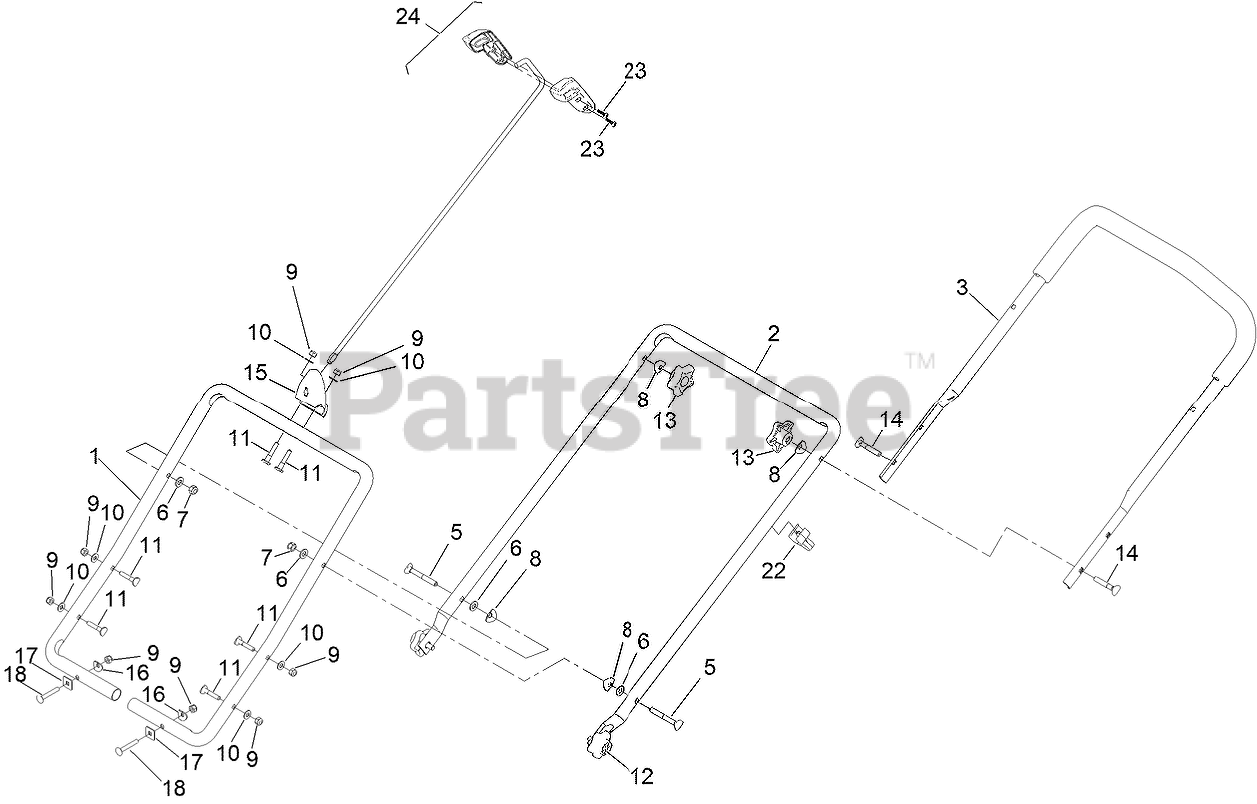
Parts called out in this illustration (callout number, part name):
1	HANDLE-LOWER
2	HANDLE-MIDDLE
3	UPPER HANDLE ASM
5	SCREW-HANDLE
6	WASHER-PLAIN
6	WASHER-FLAT
7	NUT-HEX
7	NUT-LOCK, NI
8	WASHER
8	WASHER-CUP
9	NUT-HEX
9	NUT-LOCK, NI
10	WASHER-FLAT
11	SCREW-HANDLE
12	KNOB-HANDLE
13	KNOB-HANDLE
14	SCREW-HANDLE
15	GUIDE-ROD, CHUTE
16	WASHER
17	WASHER-SQUARE
18	BOLT-CARR
18	SCREW-CARR
22	GUIDE-CABLE
23	SCREW-PPH
24	HANDLE ASM
